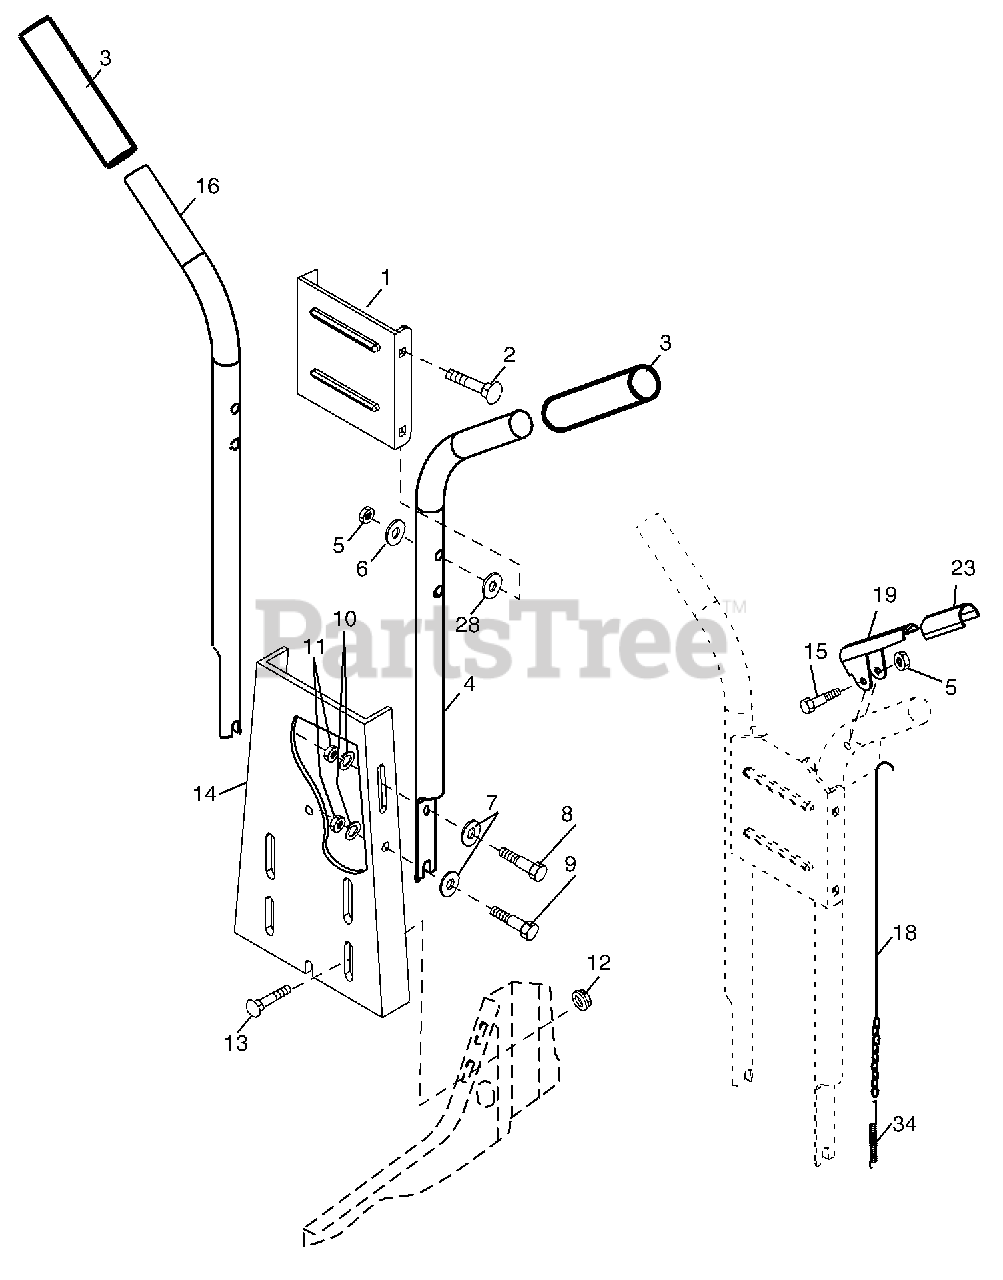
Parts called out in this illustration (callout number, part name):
1	Bracket, Handle
2	Bolt, Carriage 5/16-18 unc x 1-1/2
3	Grip, Handle
4	Handle, L.H.
5	Locknut, Crown 5/16-18
6	Washer 11/32 x 11/16 x 16 Ga.
7	Washer 3/8 x 7/8 x 14 Ga.
8	Bolt, Hex Hd. 5/16-18 x 1
9	Bolt, Hex Hd 5/16-18 x 3/4
10	Washer, Lock 5/16
11	Nut, Hex 5/16-18
12	Nut, Flanged 5/16-18
13	Bolt, Carriage 5/16-18 x 3/4
14	Panel, Handle
15	Bolt Fin Hex 5/16-18 x 1-1/2
16	Handle, R.H.
18	Cable Asm Clutch
19	Lever Clutch
23	Grip Handle
28	Washer 13/32 x 13/16 x 12 Ga.
34	Spring
